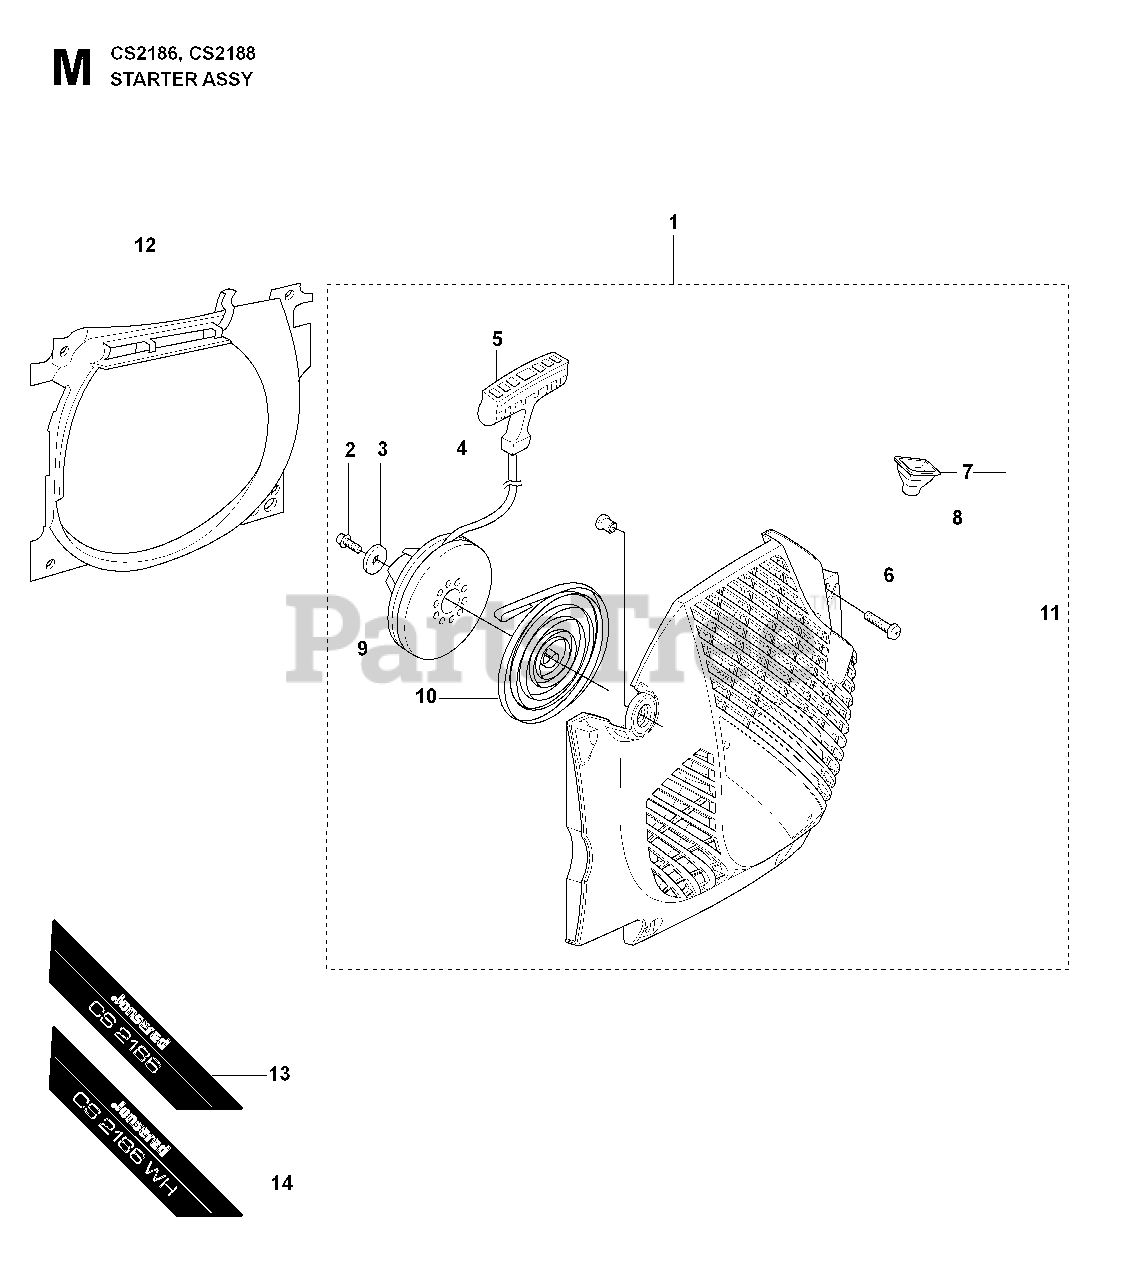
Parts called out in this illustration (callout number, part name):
1	STARTER DEVICE
2	SCREW
3	WASHER
4	STARTER ROPE
5	HANDLE
6	SCREW
7	SLEEVE
9	STARTER PULLEY
10	SPRING
11	STARTER HOUSING
12	AIR CONDUCTOR
